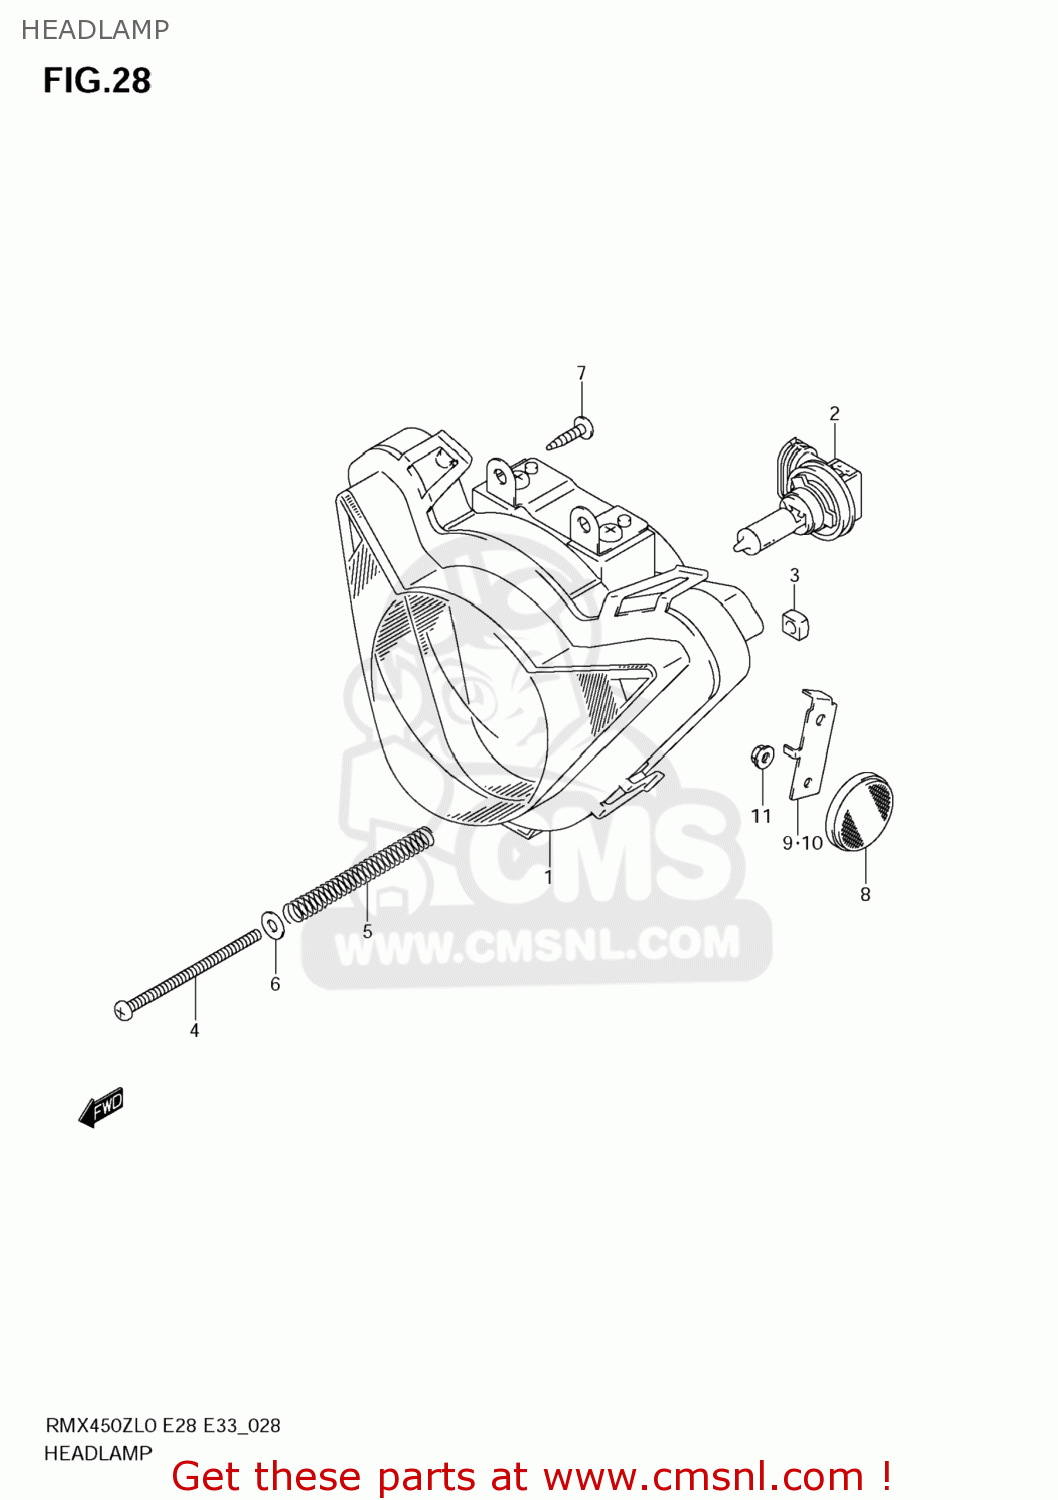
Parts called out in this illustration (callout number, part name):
1	HEADLAMP ASSY
2	BULB(12V35W,H8)
3	NUT,HEADLAMP
4	SCREW,HEADLAMP ADJUSTER
5	SPRING,HEADLAMP ADJUST
6	WASHER
7	SCREW
8	REFLECTOR,REFLEX
9	BRACKET,FR SIDE RR,R
10	BRACKET,FR SIDE RR,L
11	NUT
